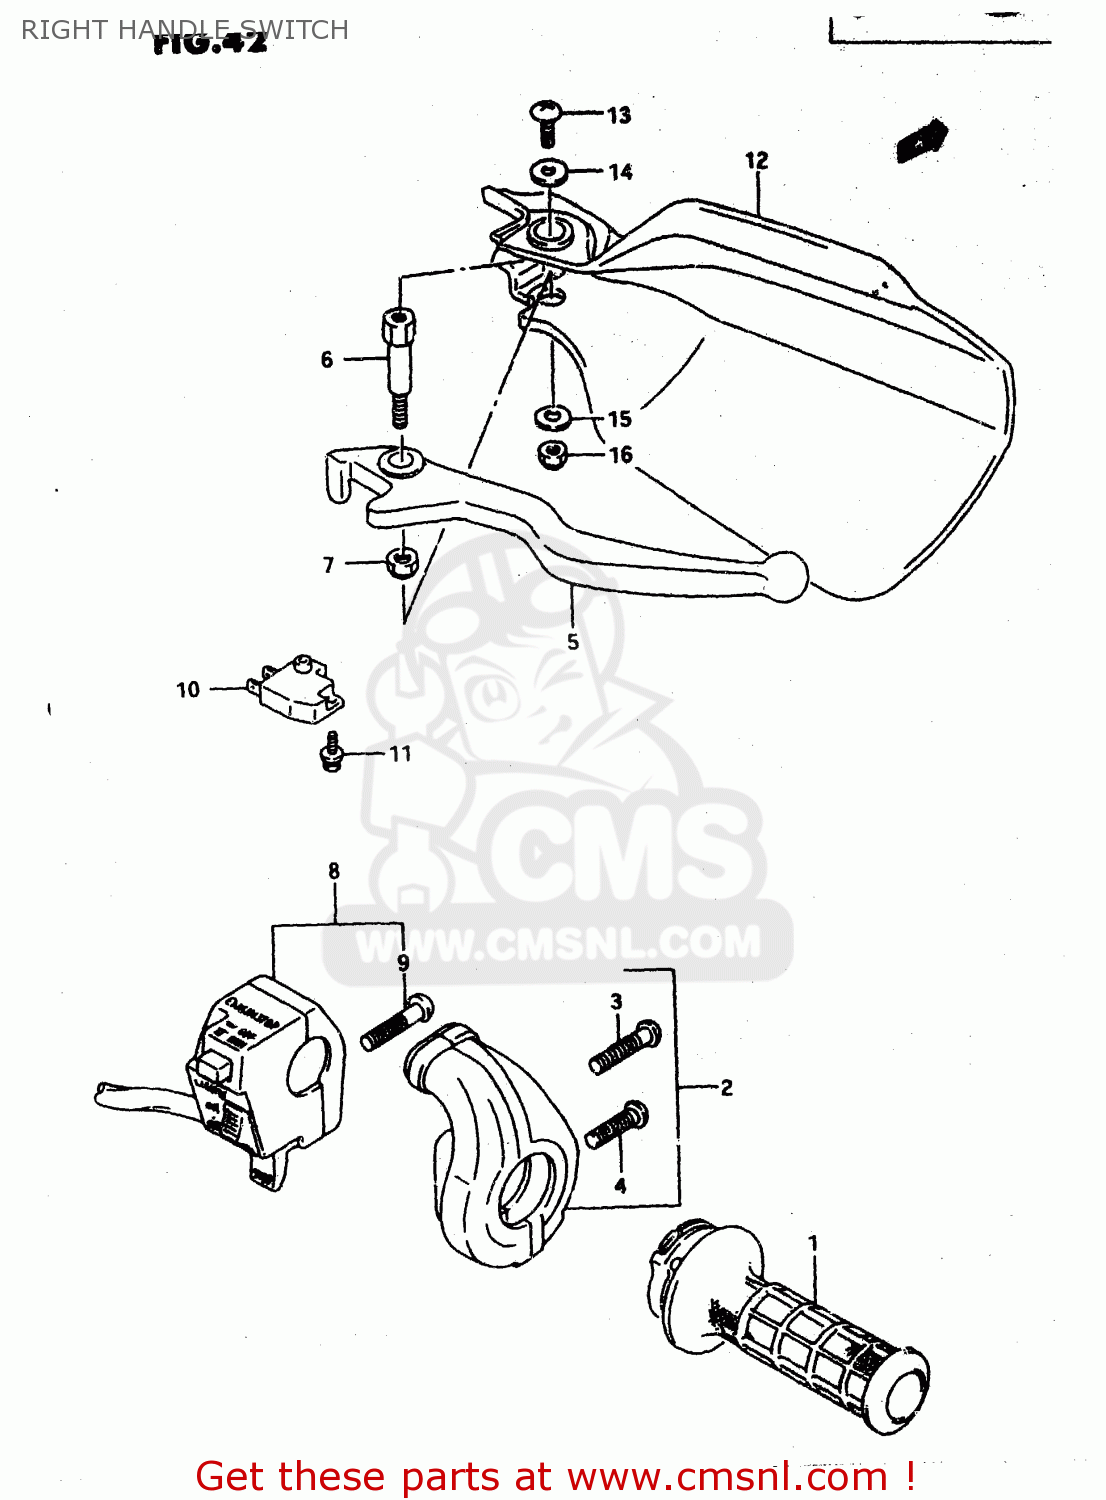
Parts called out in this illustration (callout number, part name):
1	GRIP,THROTTLE
2	CASE ASSY,THROTTLE
3	SCREW(5X25)
4	SCREW 5X20
5	LEVER,BRAKE
6	BOLT,BRAKE LEVER PIVOT
7	NUT
8	SWITCH ASSY,HANDLE,R
9	SCREW, 5X45
10	SWITCH ASSEMBLY,STOP
11	SCREW
12	COVER,KNUCKLE,R
13	SCREW
14	WASHER (5.5X16X1.2)
15	WASHER (6.5X17X1.6)
16	NUT 6MM
